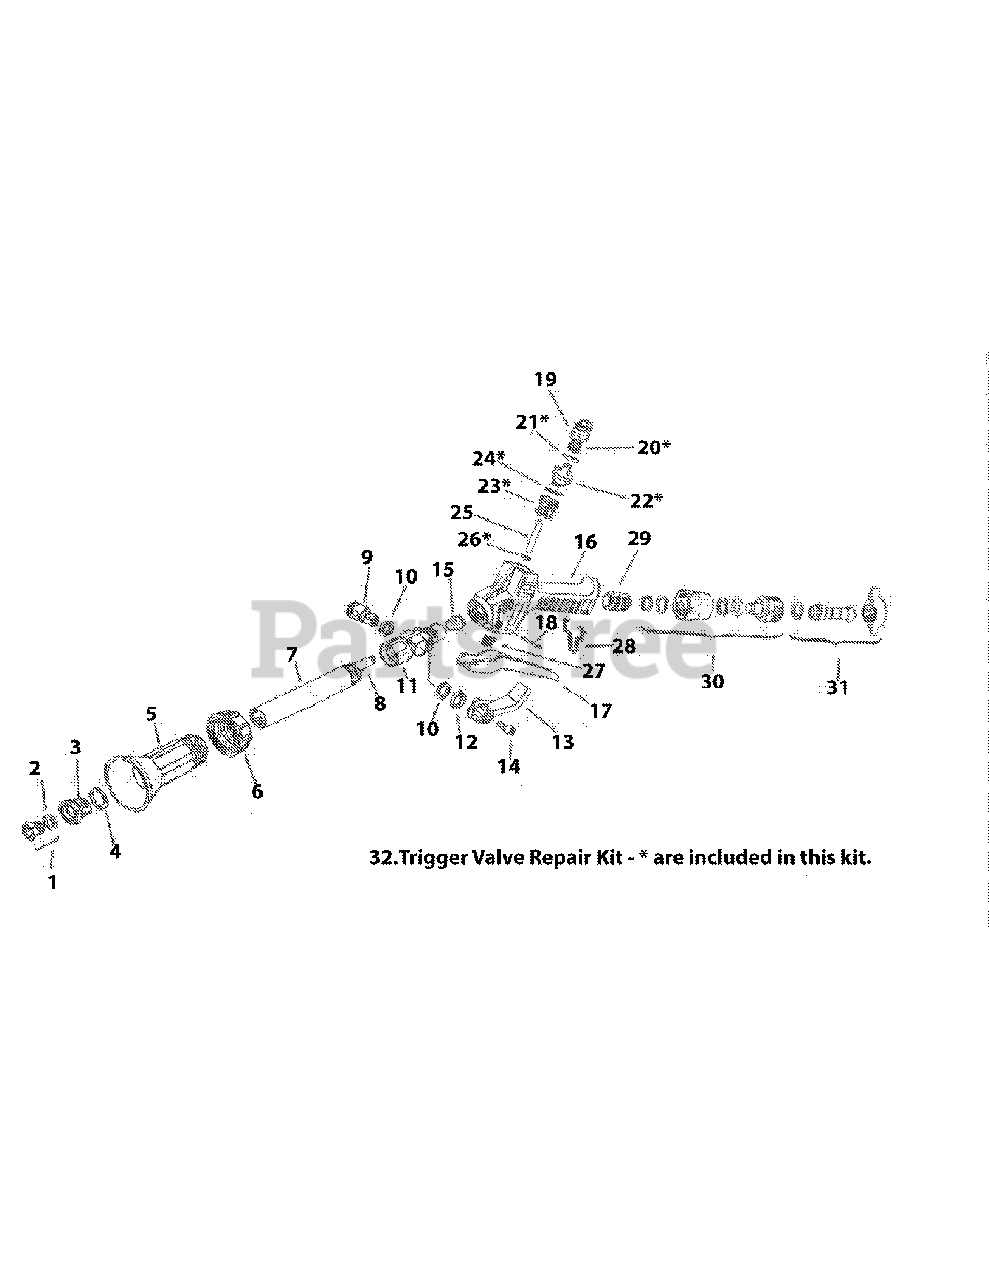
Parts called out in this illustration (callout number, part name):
1	Nozzle (Standard)
5	Nozzle Protector
6	Locking Ferrule
8	Stream Straightener
13	Adjusting Lever
15	Ferrule Insert
17	Plastic Trigger
20	Spring
21	O-ring
22	Seat
23	Valve Retainer
24	O-ring
26	Gasket
30	Swivel Connection
31	Hosebarb, Nut and Gasket
32	Trigger Valve Repair Kit Includes:
